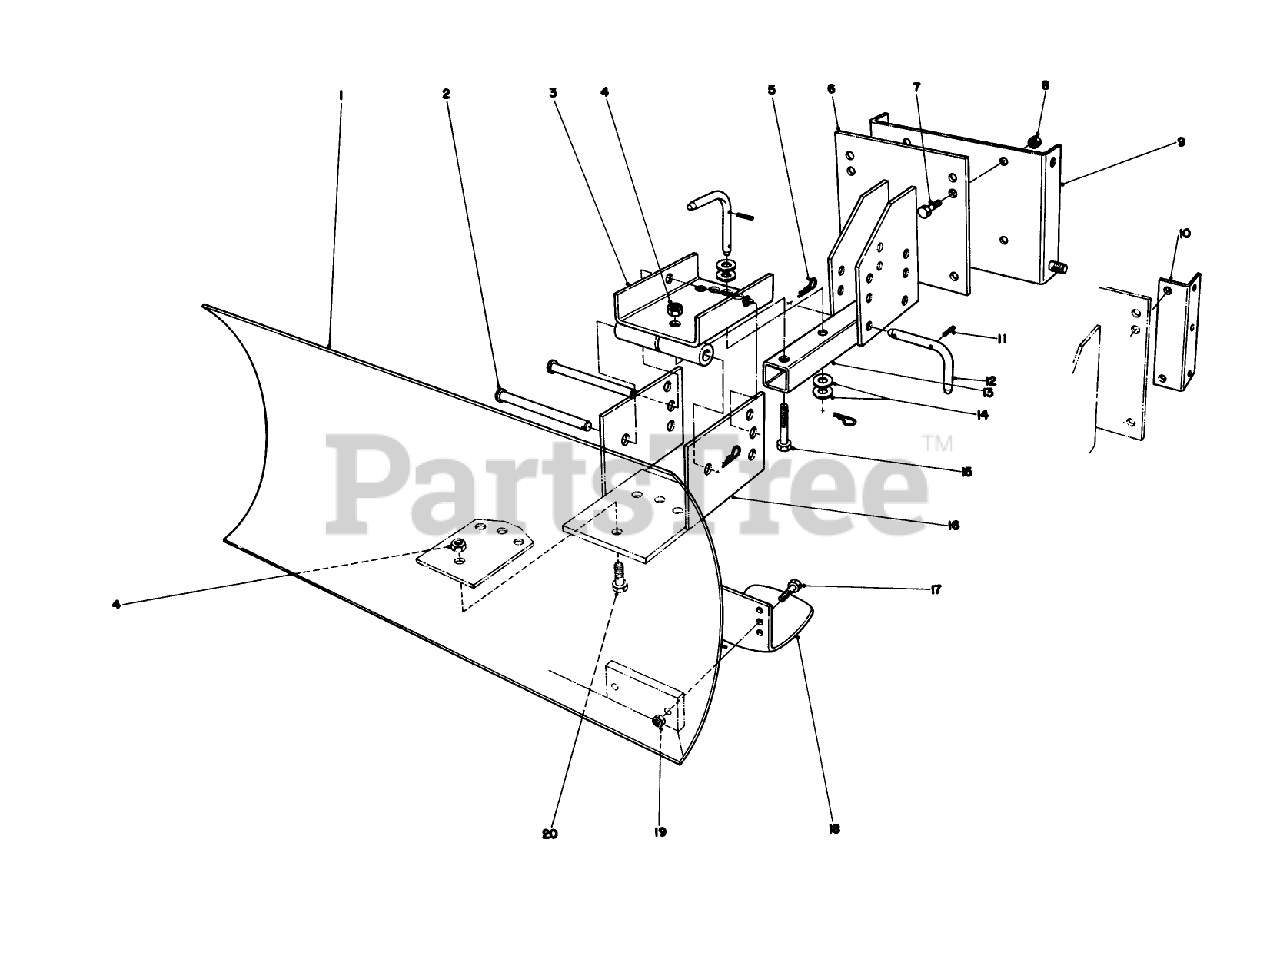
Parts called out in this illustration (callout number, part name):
1	Blade
2	PIN-CLEVIS
3	Swivel Bracket
4	1/2-13 CONELOCK NUT
5	PIN-HAIR
6	Mounting Plate
7	SCREW-HH
8	NUT-LOCK, CONE
9	Mounting Plate (Used with 826 & 1132 Units only)
10	Mounting Rail (used with 421 units only)
11	Pin-Roll
12	Pivot Pin (Incl. Ref. #11)
13	Blade Tongue
14	WASHER-FLAT
15	SCREW-HH
16	Blade Adjustment
17	SCREW-HH
19	NUT-LOCK, CONE
20	SCREW-HH
